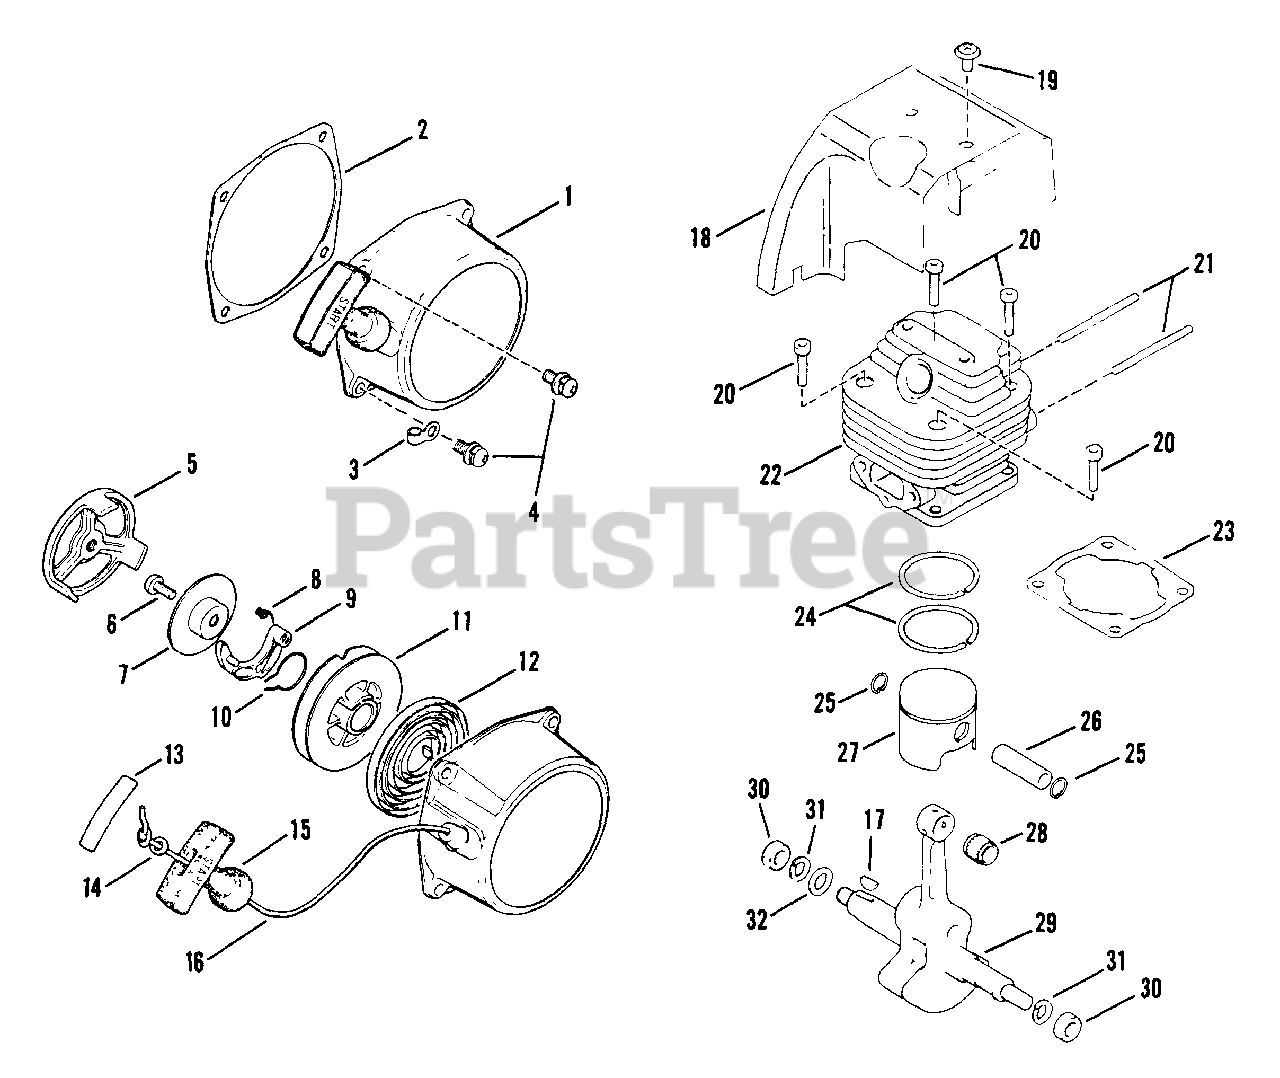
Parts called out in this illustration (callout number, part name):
1	RECOIL STARTER ASSM'Y.
2	GASKET, Recoil Starter
3	CLAMP, Fuel Tube
5	PULLEY,L Recoil Starter
7	PLATE, Friction
8	SPRING, Return
9	RATCHET
10	SPRING, Friction
12	SPRING, Spiral
13	TAPE, Knob
15	KNOB, Recoil Starter
16	ROPE, Recoil Starter
18	COVER, Cylinder
20	BOLT, Cylinder
21	STUD BOLT
22	CYLINDER
23	GASKET, Cylinder
24	RING, Piston
25	SNAP-RING, Piston Pin
26	PISTON
27	PIN, Piston
28	BEARING, Needle
29	CRANKSHAFT
30	NUT, Crankshaft
31	WASHER, Spring
